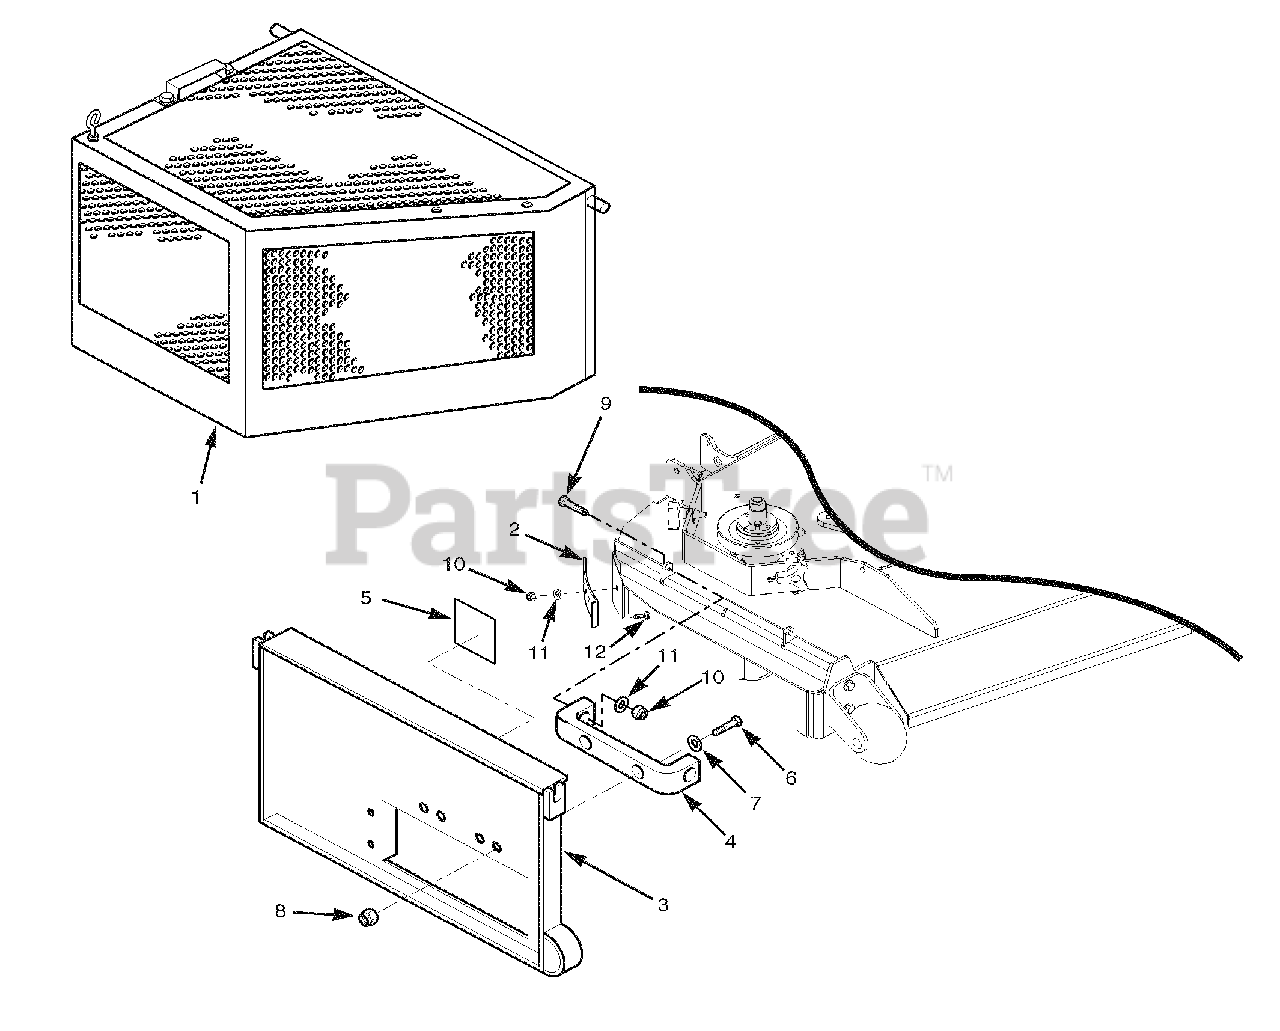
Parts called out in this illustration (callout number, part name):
1	Catcher Box
2	Filler Plate, Grass Catcher Velocity Plus Decks
3	Cover Weldment With Decal
4	Bracket, Mounting
5	Decal, Danger
6	Bolt, 3/8-16 x 1-1/2" Hex Head
7	Flat Washer, 3/8"
8	Nut, 3/8-16 Elastic Stop
9	Bolt, 5/16-18 x 1-1/4" Hex Head
10	Nut, 5/16-18 Elastic Stop
11	Flat Washer, 5/16"
12	Bolt, Carriage 5/16-18 x 3/4"
